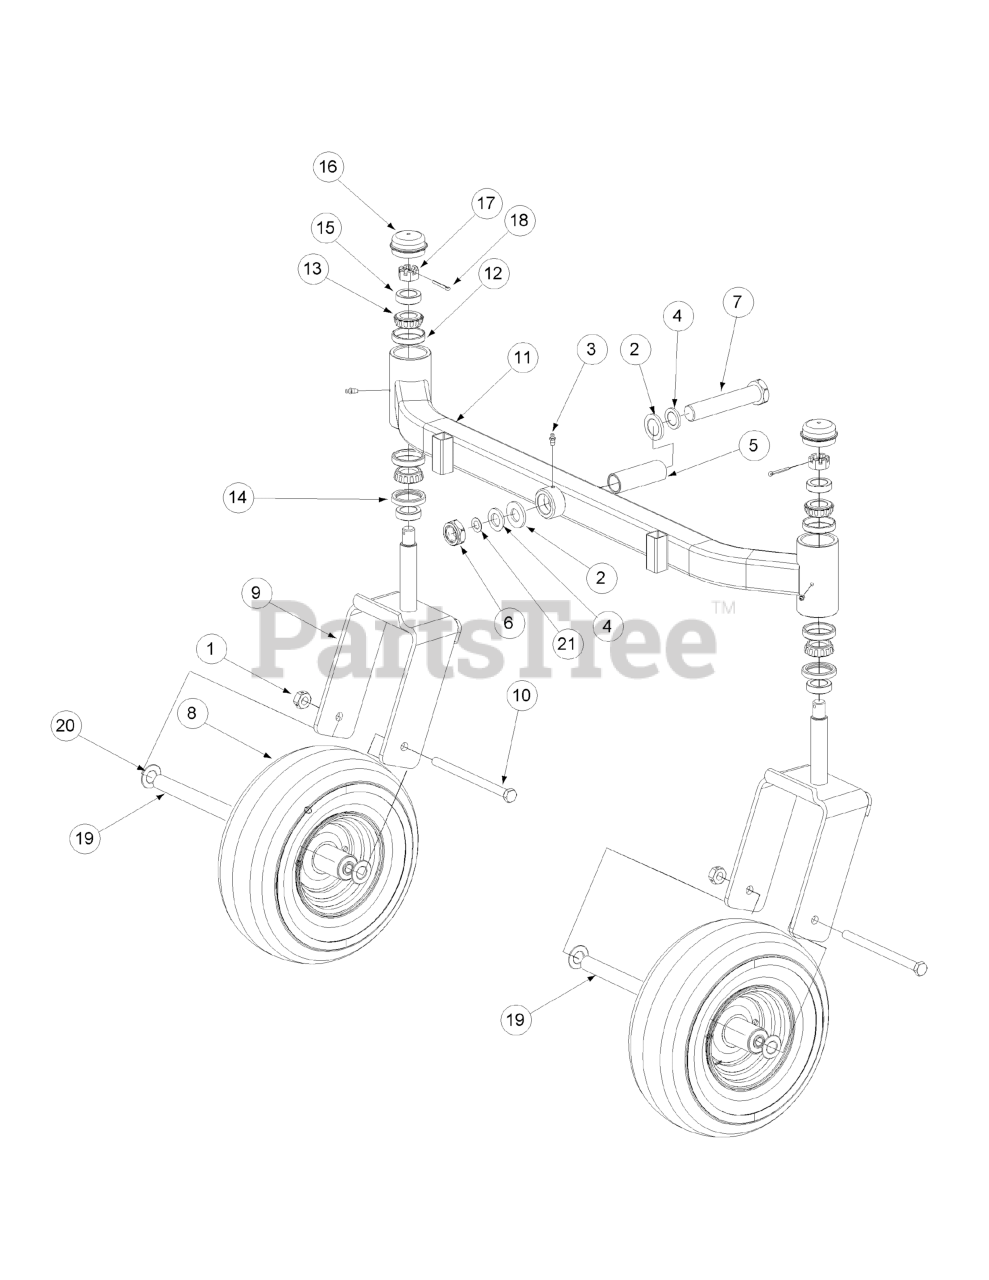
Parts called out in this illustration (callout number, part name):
1	Nut, 1/2-20, Center Lock
2	Bell Washer, 1.25 ID
3	Grease Fitting
4	Flat Washer, 1.00 ID
5	Spacer, 1.005 ID x 1.25 OD x 3.6
6	Nut, Jam, 1.0-14, Insert Lock
7	Hex Cap Screw, 1-14 x 5.0
8	Wheel Assembly, 13 x 6.50 x 6, White, includes:
9	Yoke, Caster Wheel
10	HHCS, 1/2-20, 7.50
11	Front Axle Assembly
12	Cup Bearing
13	Bearing Cone
14	Seal
15	Ring Seal
16	Grease Cap, 1.986 OD
17	Slotted Nut, 3/4-16
18	Cotter Pin, 5/32, 1.25
19	Wheel Spacer
20	Spacer, .812 ID x .218LG
21	Retainer Extension, Self Locking
